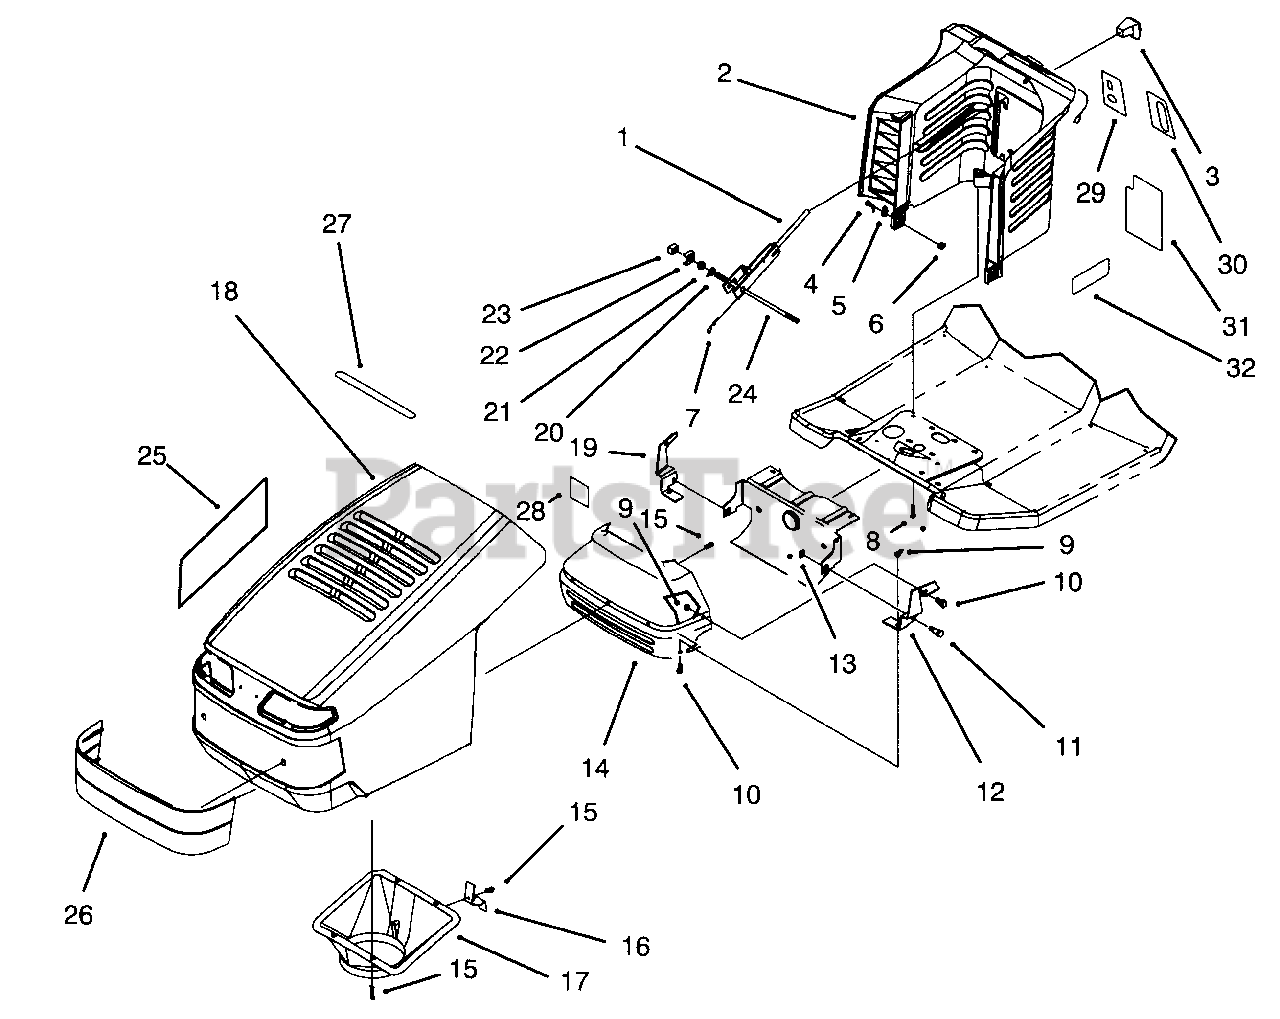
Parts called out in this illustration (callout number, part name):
1	Lever-Deck Engage
2	Tower-Steering
3	Knob-Engage Lever
4	Screw-Hex Hd. Cap
5	Washer-Flat
6	Nut-Lock
7	Pin-Cotter
8	Screw-Plastite
9	Nut-Lock
10	Screw-Hex Hd. Cap
11	Bolt-Shoulder
12	Bracket-Hood Pivot L.H.
13	Nut-Retained
14	Shield-Heat
15	Screw-Plastite
16	Latch-Hood
17	Duct-Hood Air
18	Hood
19	Bracket-Hood Pivot R.H.
20	Washer-Flat
21	Nut-Flange
22	Clamp-Pivot Rod
23	Nut-Wedge
24	Rod-Tower Pivot
25	Decal-Hood R.H.
26	Panel-Grille
27	Decal-Air Duct
28	Patch-Heat Tape
29	Decal-Ignition/Lights (Model No. 81180 & 81181 Only)
30	Decal-Throttle
31	Decal-Deck Engage
32	Decal-Tower LT10 (Model No. 81140 Only)
